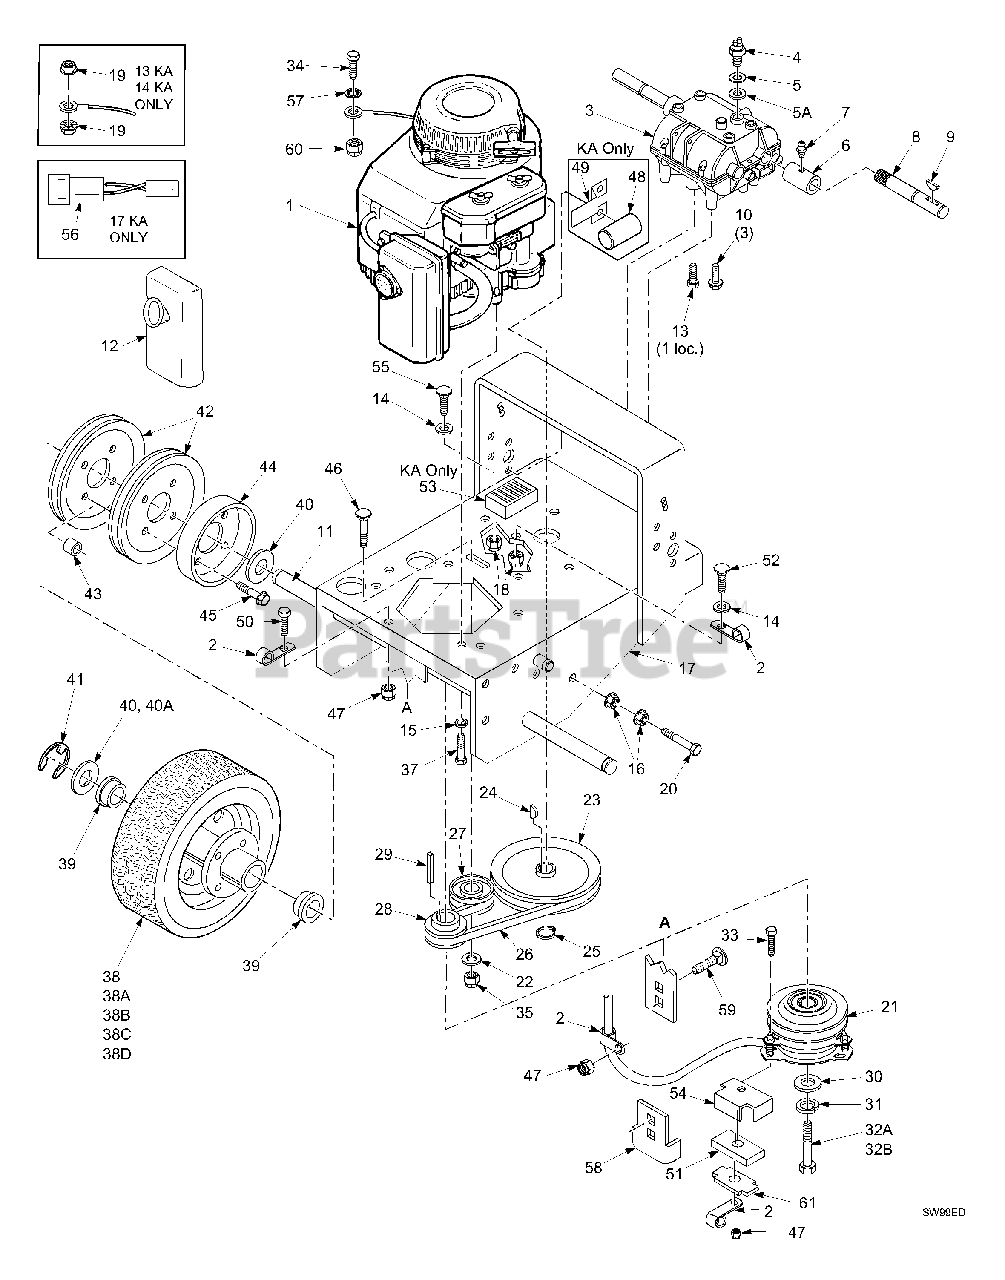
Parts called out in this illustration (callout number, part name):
1	Engine, 17HP Kawasaki (FH500V)
2	Cable Clamp
3	Transmission, 5-speed
4	Neutral Safety Switch
5	Fibre Washer, thin
5A	Fibre Washer, thick
6	Coupler, Jackshaft
7	Grease Fitting, straight 1/4-28
8	Jackshaft
9	Key, Hi-Pro #9
10	Bolt, 5/16-18 X 3/4" Carriage
11	Wheel Axle
12	17KA Muffler
13	Bolt, 5/16-18 X 3/4" Hex Head
14	Flat Washer 1/4" (.312 X .75 X .065)
15	Lock Wshr. 5/16"
16	Nut, 3/8-16 Serrated Flange
17	Engine Deck
18	Nut, 1/4-20 Elastic Stop
19	Nut, 5/16-18 Serrated Flange
20	Bolt, 3/8-16 x 3-3/4" Hex Head
21	Electric Clutch (Ogura)
22	Washer, 3/8" (.391 x .938 x .105)
23	Pulley, Transmission Input
24	Key, Woodruff #9
25	Retaining Ring, 5/8" Ext, Basic
26	Belt, Transmission Drive
27	Idler Pulley, Transmission
28	Pulley, Traction Drive
29	Key, 1/4 x 1/4 x 3/4"
30	Flat Washer, 7/16" Special
31	Lock Washer, 7/16"
32A	Bolt, 7/16-20 x2-1/2" Hex Head
32B	Cpsrw, M10-1.5 x 55 Metric Hex Hd
33	Bolt, 5/16-18 x 1-3/4" Hex Head
35	Nut, 3/8-16 Elastic Stop
37	Bolt, M8-1.25 x M25 Metric Hex Hd
38	Wheel Assembly
38A	Tire, 13 x 6.50-6, 2-ply
38B	Rim & Bearing Assembly
38D	Rim Assembly
40	Washer, 1-1/16 x 1-3/4 x 12 ga
40A	Washer, 1-1/16 x 1-1/2 x 18 ga
41	Retaining Ring, 1" Ext.- "E"
42	Pulley, Wheel Drive
43	Spacer, Wheel Pulley
44	Brake Drum
45	Bolt, 5/16-18 x 1-1/2" Serrated flange
46	Bolt, 3/8-16 x 2" Carriage
47	Nut, 5/16-18 Elastic Stop
48	Condenser
49	Bracket, Capacitor
50	Bolt, 5/16-18 x 1" Hex Head
51	Rubber Pad, Clutch Stop
52	Bolt, 1/4-20 x 3/4" Carriage
53	Rectifier
54	Backing Plate
56	Wire Harness Adapter,
57	Lock Washer Internal Tooth
58	Anti Rotation Bracket
59	Bolt, 5/16-18 x 1" Carriage
60	Nut, 1/4-20 Elastic Stop
61	Plate, Backing
